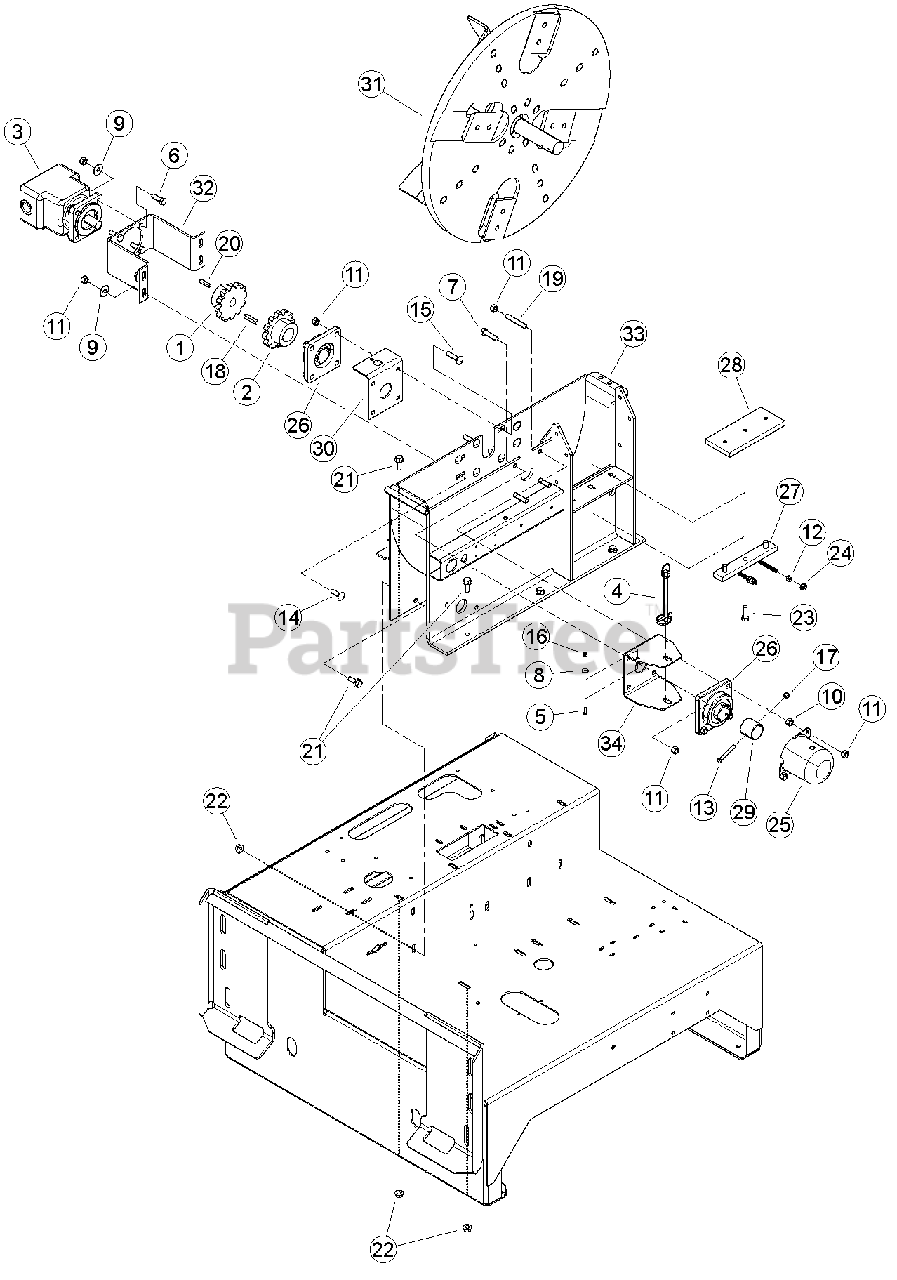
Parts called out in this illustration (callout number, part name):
1	COUPLER, CHAIN 1" ID
2	COUPLER, CHAIN 1-3/4" ID
3	MOTOR, 3.45 CU IN HYDRAULIC
4	PIN, HITCH 1/2 X 6-1/2 W/ LYNCH
5	BOLT, 1/4-20 X 3/4 GR5 HEX HD
6	BOLT, 1/2-13 X 1-1/2 HEX HD GR5
7	BOLT, 1/2-13 X 2 GR5 HEX CAPSCREW
8	WASHER, 1/4 FLAT
9	WASHER, 1/2 FLAT
10	NUT, 1/2-13 HEX
11	NUT, 1/2-13 GR5 CENTERLOCK GRB
12	NUT, 3/8-16 SERRATED FLANGE
13	BOLT, 3/8 X 2-1/2 GR5 HHCS ZP
14	BOLT, 1/2 X 1-1/2" GR5 ZP CRG
15	BOLT, 1/2-13 X 2 GR5 CRG
16	NUT, 1/4-20 NE NYLOCK
17	NUT, 3/8-16 NE NYLOCK
18	KEY, 3/8 SQ X 2" LG PLAIN
19	STUD, 1/2"-13 X 3" LG B7 ZP
20	KEY, 5/16 X 1-1/2 SQUARE
21	BOLT, 1/2-13 X 1-1/4 SERRATED FLANGE
22	NUT, 1/2 SPIRAL LOCK NC ZP
23	BOLT, 1/2 X 1-1/2 GR8 NC ZP HEX HD
24	NUT, 3/8-16 NYLOCK FLANGE
25	CAP, LARGE SHAFT
26	BEARING, 1-3/4 4 BOLT FLANGE
27	WELDMENT, BLOCK ADJUSTOR
28	PLATE, CHIPPER BOTTOM
29	COLLAR, CHIPPER LOCK
30	WELDMENT, CONTROL ARM
31	ASSEMBLY, 8" CHIPPER ROTOR
32	MOUNT, HYDRAULIC MOTOR
33	WELDMENT, ROTOR HOUSING
34	BRACKET, ROTOR LOCK
